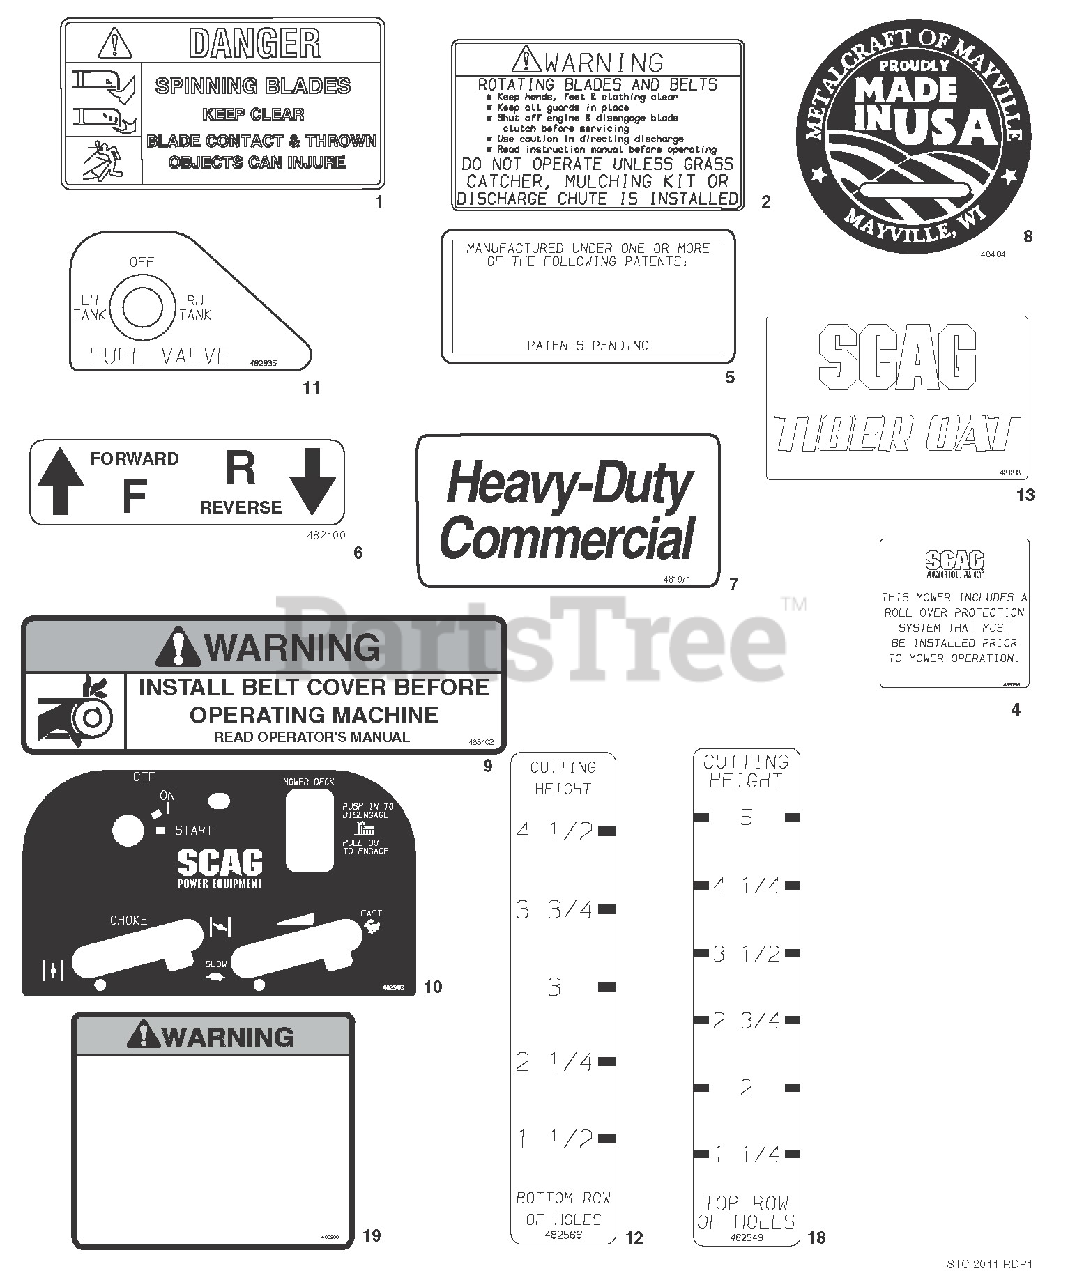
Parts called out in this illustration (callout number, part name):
1	Decal, Danger-Spinning Blades
2	Decal, Warning-Rotating Blades
4	Decal, ROPS
5	Decal, Patents
6	Decal, Traction Control
7	Decal, Heavy Duty Commercial
8	Decal, Metalcraft - Made in USA
9	Decal, Belt Cover
10	Decal, Instrument Panel
11	Decal, Fuel Valve Position
12	Decal, Cutting Height Bottom Row of Holes
13	Decal, Tiger Cat
18	Decal, Cutting Height Top Row of Holes
19	Decal, Warning Spark Arrestor
